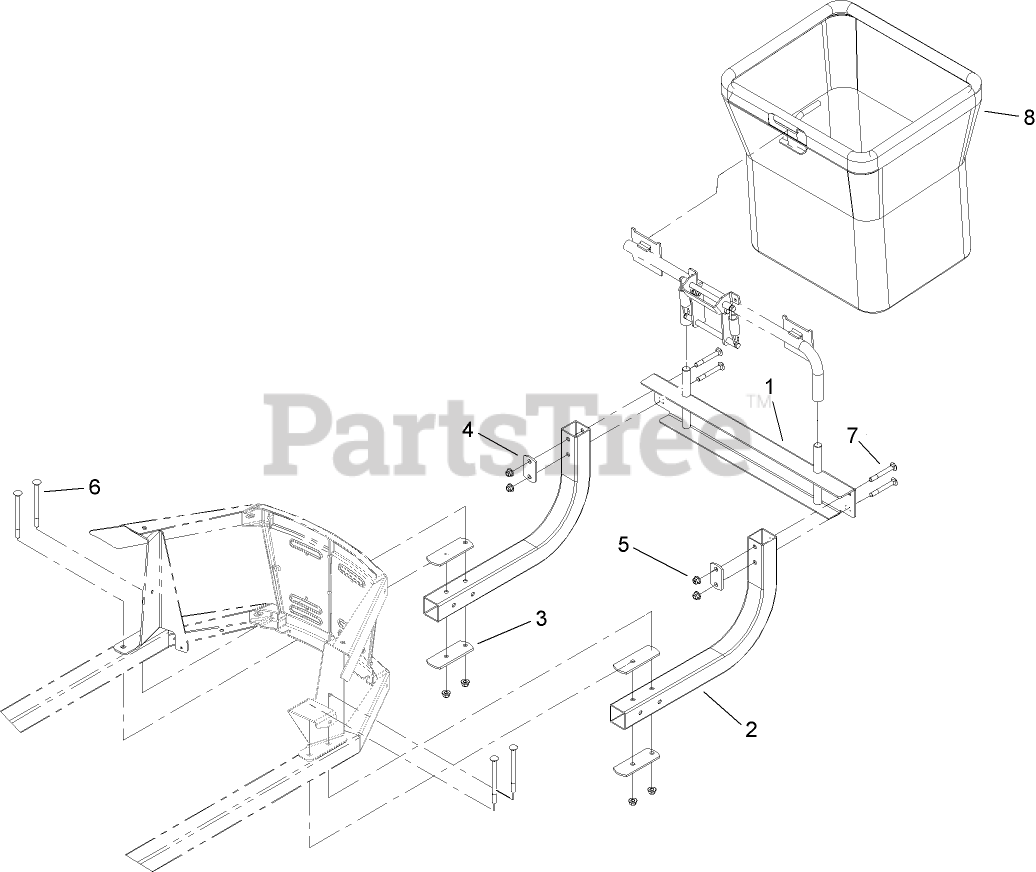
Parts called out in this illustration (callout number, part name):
1	BAGGER HITCH ASM
2	TUBE-HITCH, BAGGER
3	PLATE-STIFFENER
4	PLATE-STIFFENER
5	NUT-HF, NI
6	BOLT-CARR
7	SCREW-CARR
8	BAG ASM
